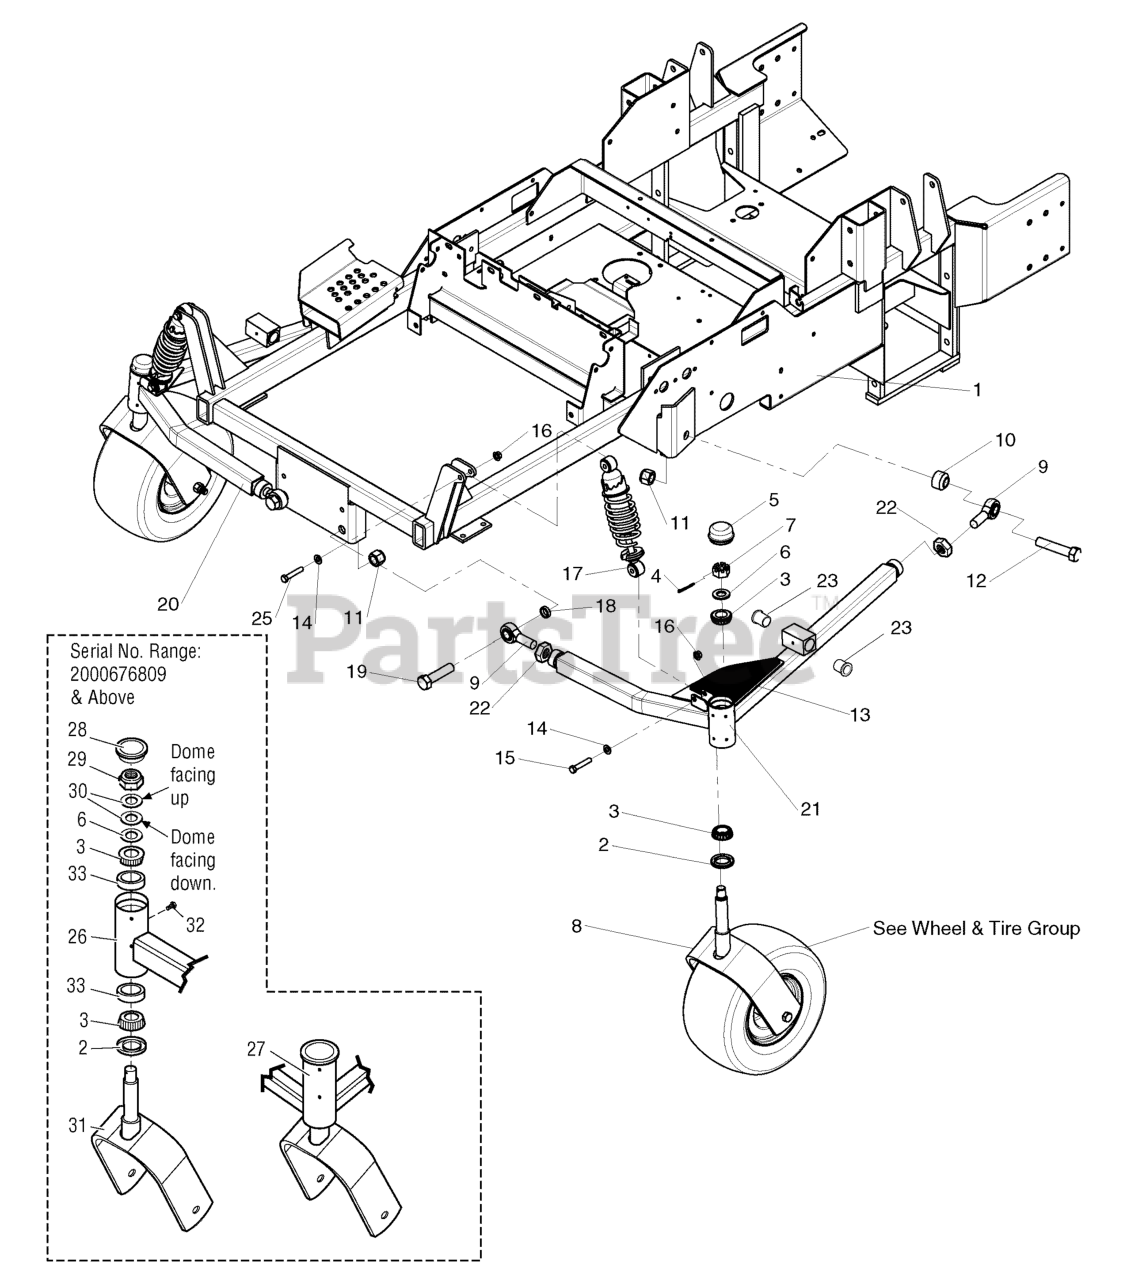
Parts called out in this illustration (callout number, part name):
1	WELD, MAIN FRAME IS5000 - RED
1	WELD, MAIN FRAME IS5100 - RED
2	SEAL, GREASE
3	BEARING, TAPERED ROLLER, 1"
4	3/16 X 1-1/2 COTTER PIN
5	CAP, DUST
6	WASHER, 3/4 SAE
7	NUT, 3/4-16 HEX SLOTTED
8	WELD, CASTER YOKE - RED
9	BALL JOINT, 3/4-16, MALE
10	SPACER, .75 X 1.50 X 1.00
11	NUT, 3/4-16 HEX NYLON LOCK
12	BOLT, 3/4-16 X 3-1/2" YZ GD5
13	SAFETY WALK, IS5000Z A-ARM STEP
14	WASHER, 3/8 SAE
15	BOLT, 3/8-16 X 2, GD5, CZ
16	NUT, 3/8-16 HEX NYLOCK FLANGE
17	COIL-OVER SHOCK ASSEMBLY
18	SPACER, .75 X 1.50 X 1.00
19	BOLT, 3/4-16 X 3-1/2" YZ GD5
20	ASSM, SUSPENSION ARM RH - RED
21	ASSM, SUSPENSION ARM LH - RED
22	NUT, 3/4-16 HEX JAM
23	BUSHING, 1.00 X 1.13 X 1.38, PLASTIC
25	BOLT, 3/8-16 X 2-1/4" GD5 CZ
26	WELD, SUSPENSION ARM - RH - RED
27	WELD, SUSPENSION ARM - LH - RED
28	CAP, GREASE, LOW PROFILE
29	NUT, 3/4-16, HEX JAM NYLON LOCK
30	BELLEVILLE WASHER, 1.500 X .755
31	WELD, CASTER YOKE - RED
32	BOLT, 1/4-28 X 1/2, GD5 YZ
33	BEARING CUP
